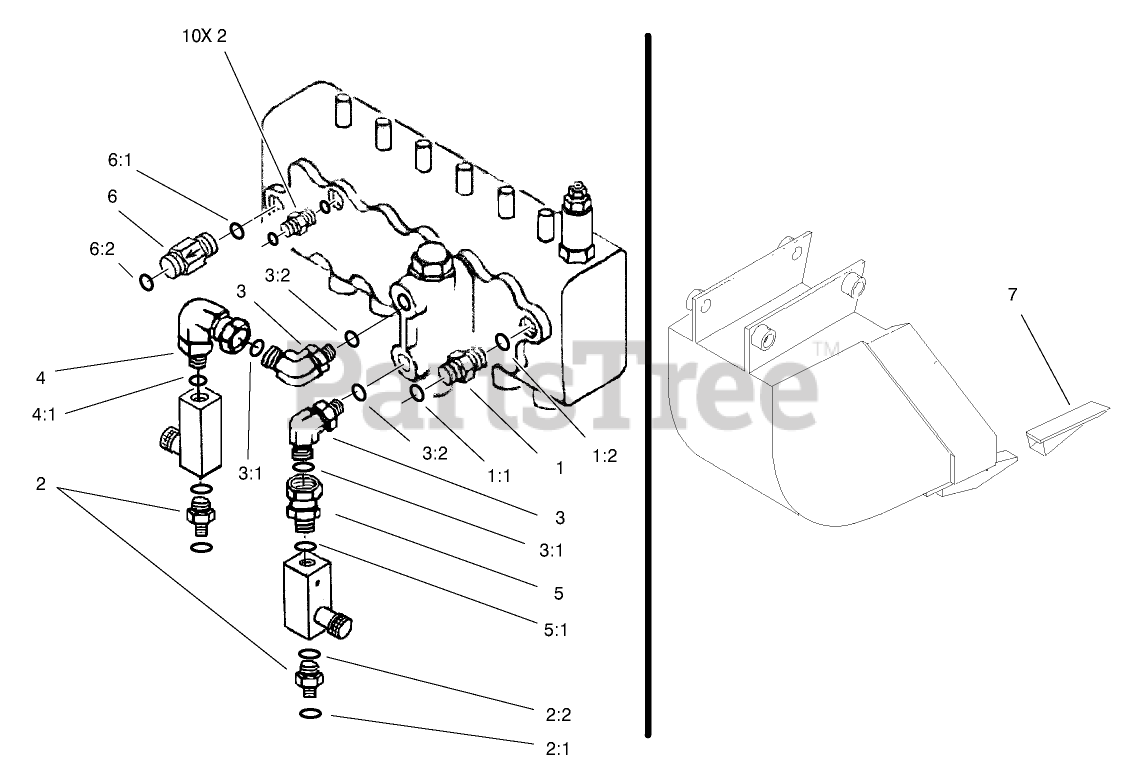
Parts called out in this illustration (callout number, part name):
1	FITTING-STRAIGHT
1:1	O-RING
1:2	O-RING
2	FITTING-STRAIGHT
2:1	O-Ring
2:2	O-RING
3	FITTING-ELBOW, 90 DEG
3:1	O-RING
3:2	O-RING
4	FITTING-SWIVEL, 90 DEG
4:1	O-RING
5	FITTING-SWIVEL, STRAIGHT
5:1	O-RING
6	VALVE-CHECK
6:1	O-RING
6:2	O-RING
7	TOOTH-BUCKET
